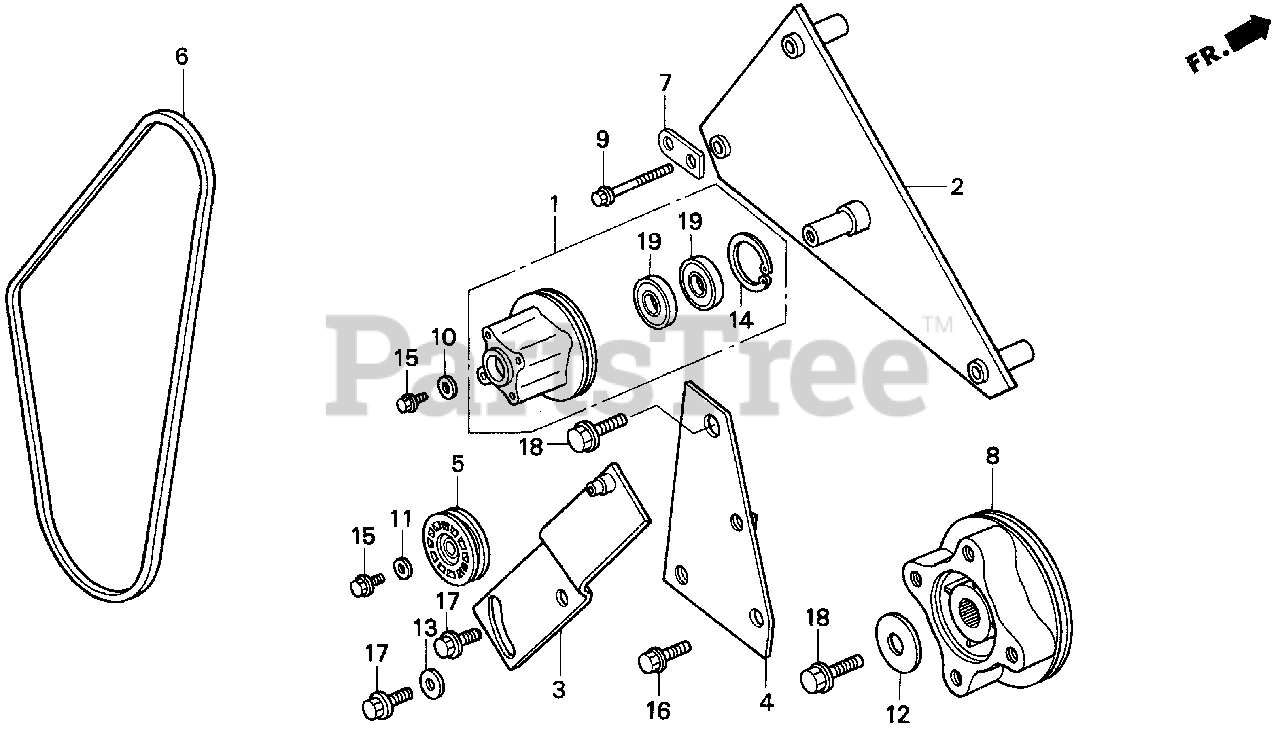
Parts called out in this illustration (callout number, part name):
1	PULLEY ASSY., COOLING FAN
2	BRACKET, COOLING FAN
3	ARM, TENSION
4	PLATE, TENSIONER ARM
5	PULLEY, TENSIONER (65MM)
6	BELT, ALTERNATOR (BANDO)
7	BRACKET, WIRE HARNESS CLIP
8	JOINT, PROPELLER SHAFT
9	BOLT, FLANGE (6X50)
10	WASHER, GEARSHIFT DRUM SIDE
11	WASHER (6MM)
12	WASHER (10.5X40X4)
13	WASHER, PLAIN (10MM)
14	CIRCLIP (INNER) (32MM)
15	BOLT, FLANGE (6X12)
16	BOLT, FLANGE (8X20)
17	BOLT, FLANGE (10X20)
18	BOLT, FLANGE (10X25)
19	BEARING, RADIAL BALL (6201UU)
